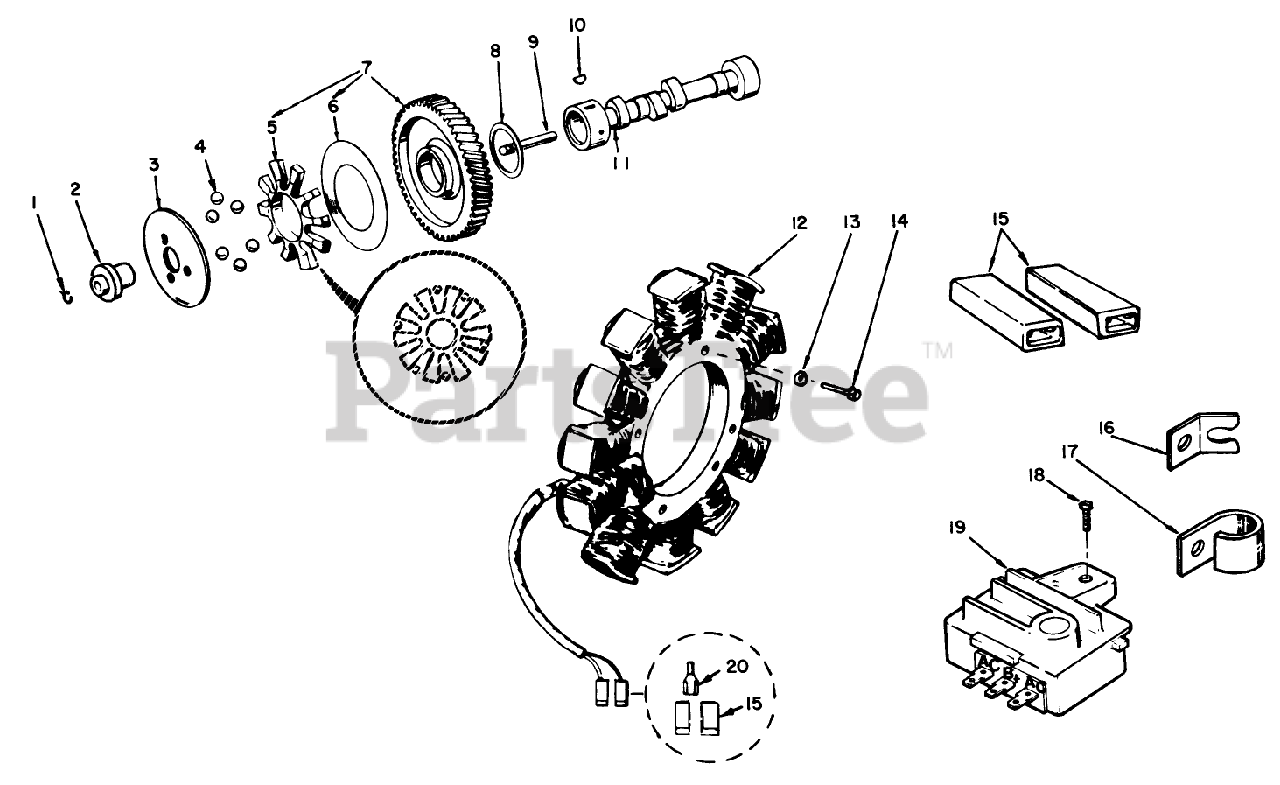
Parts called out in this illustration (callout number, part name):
1	Ring, Retaining
2	Hub, Governor Cup
3	Cup, Governor
4	Ball, Governor
5	Spacer, Flyball
6	Plate, Flyball
7	Gear, Camshaft(Incl. Ref. #5 6)
8	Washer, Thrust
9	Pin, Center
10	Key Crankshaft Gear
11	Camshaft (Incl. Ref. #9)
12	Stator (Incl. Ref. #15 20)
13	Washer-Lock
14	Screw-Machine, Round Hd.
15	Body, Terminal Connector (AC Terminals)
16	Bracket, Alternator Lead
17	INSTALLATION INSTRUCTIONS
18	Screw-Cap Hex Washer Hd.
19	Regulator Voltage
20	INSTALLATION INSTRUCTION
